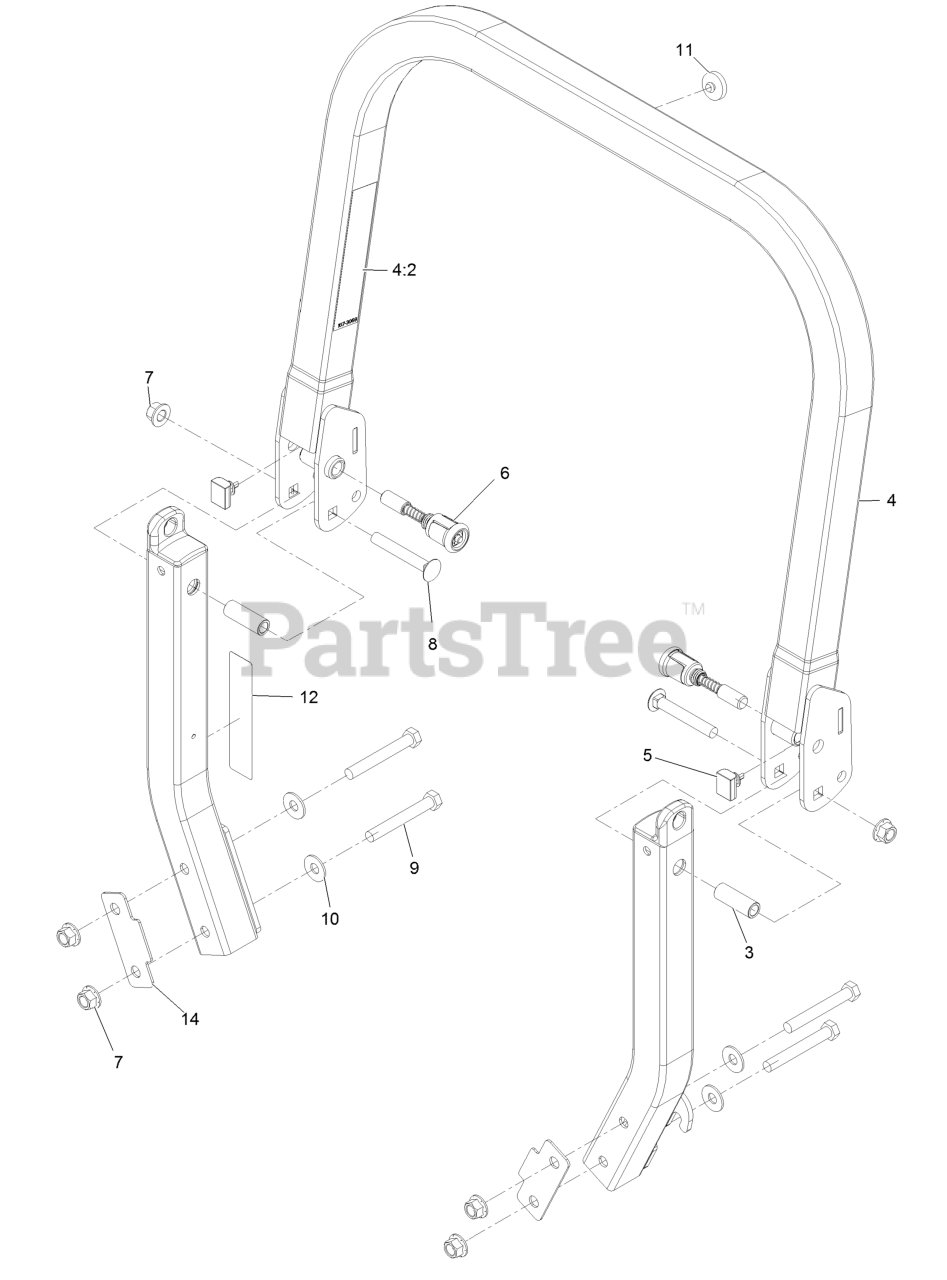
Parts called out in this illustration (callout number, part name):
4	UPPER ROPS ASM
4:2	DECAL-WARNING
5	BUMPER-ROPS
6	PIN-SPRING
7	Nut-Lock 1/2-13
8	SCREW-CARR
9	WASHER-LOCK
10	WASHER-SPRING
11	BUMPER-PUSH-IN, RUBBER
12	DECAL-CAUTION, FUEL VENT
